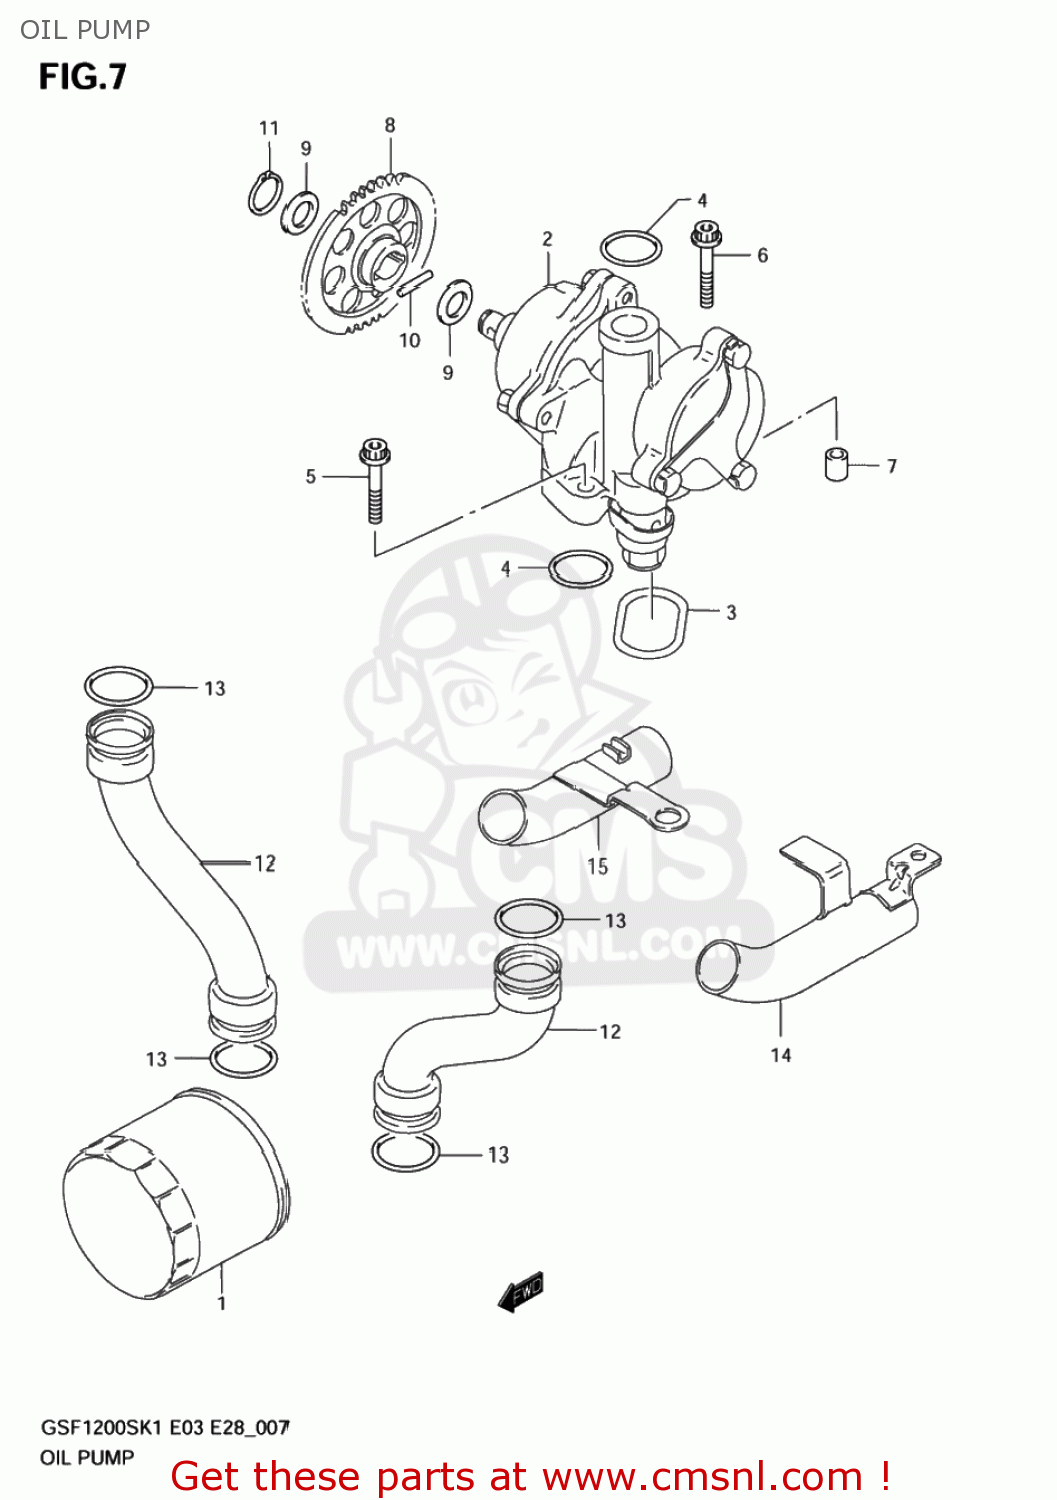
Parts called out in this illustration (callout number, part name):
1	FILTER ASSY,EN
2	PUMP ASSY,OIL
3	O RING,OIL PUMP
4	O RING(D:3.2,ID:17.8)
5	BOLT(6X30)
6	BOLT(6X35)
7	PIN
8	GEAR,OIL PUMP DRIVEN(NT:37)
9	SHIM
10	PIN(5X18)
11	CIRCLIP,12 MM
12	PIPE,OIL OUTLET
13	O RING(D:3.7,ID:21.7)
14	PIPE,OIL OUTLET UNDER,L
15	PIPE,OIL OUTLET UNDER,R
